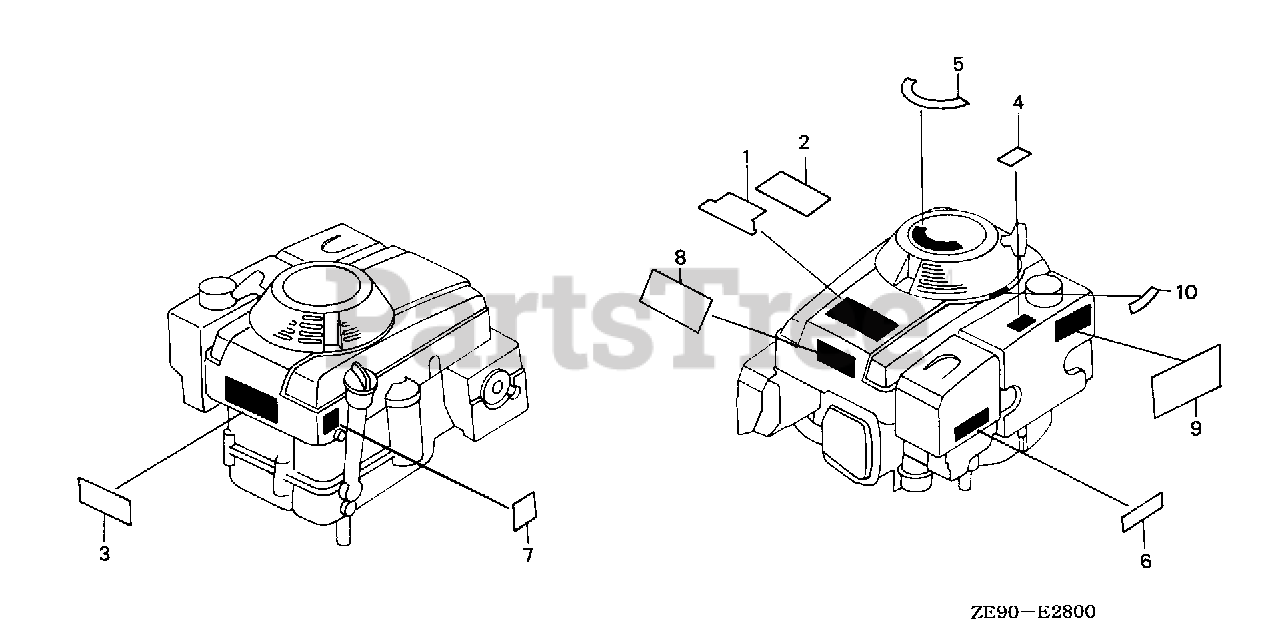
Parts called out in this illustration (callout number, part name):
1	EMBLEM, TOP COVER (E) (NOT AVAILABLE)
3	MARK, CAUTION (NOT AVAILABLE)
4	LABEL, FUEL CAUTION (ENGLISH)
5	MARK, EASY START (ENGLISH)
6	MARK, AIR CLEANER CAUTION
7	MARK, OIL CAUTION
